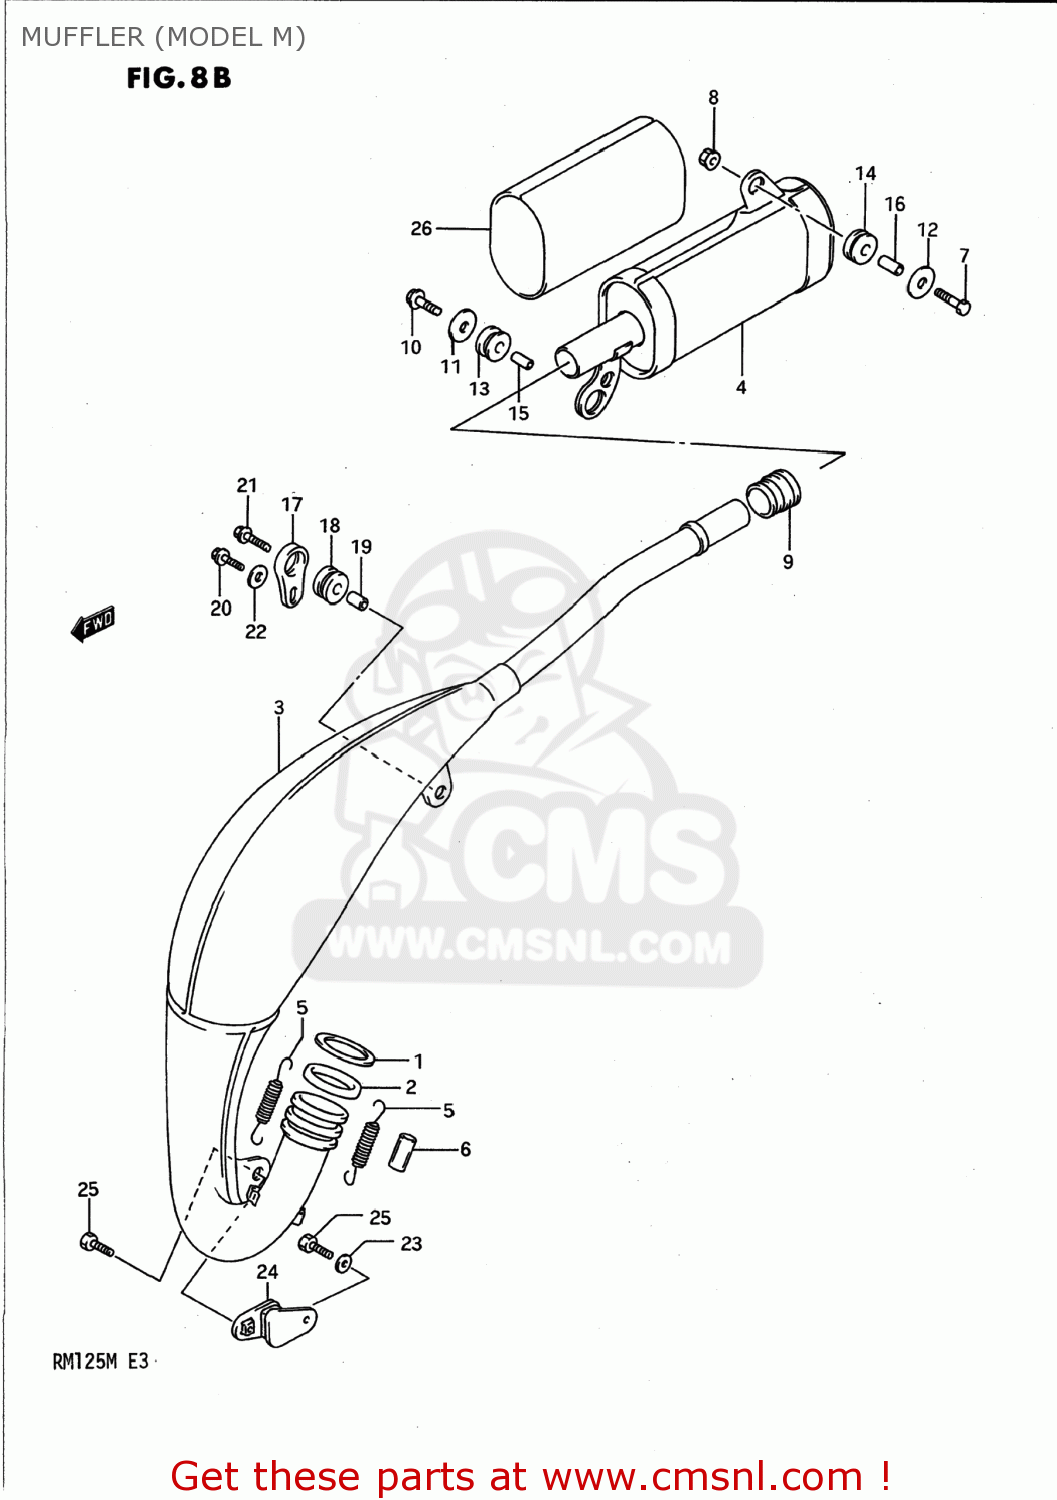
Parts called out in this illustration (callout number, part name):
1	WASHER,EXHAUST PIPE
2	O RING,EXHAUST PIPE
3	BODY,MUFFLER,FIRST
4	BODY,MUFFLER
5	SPRING
6	HOSE
7	BOLT
8	NUT
9	CONNECTOR,MUFFLER
10	BOLT
11	WASHER (6.5X24X1.2)
12	WASHER(8.5X26X1.2)
13	CUSHION
14	CUSHION
15	SPACER (6.8X10X9)
16	SPACER (8.1X11.5X13)
17	PLATE,MUFFLER MTG
18	CUSHION,MUFFLER
19	SPACER (6.4X9X13.5)
20	BOLT
21	BOLT
22	WASHER (6.5X20X1.2)
23	WASHER
24	DAMPER,MUFFLER SUPPORT
25	BOLT
26	SILENCER,MUFFLER
